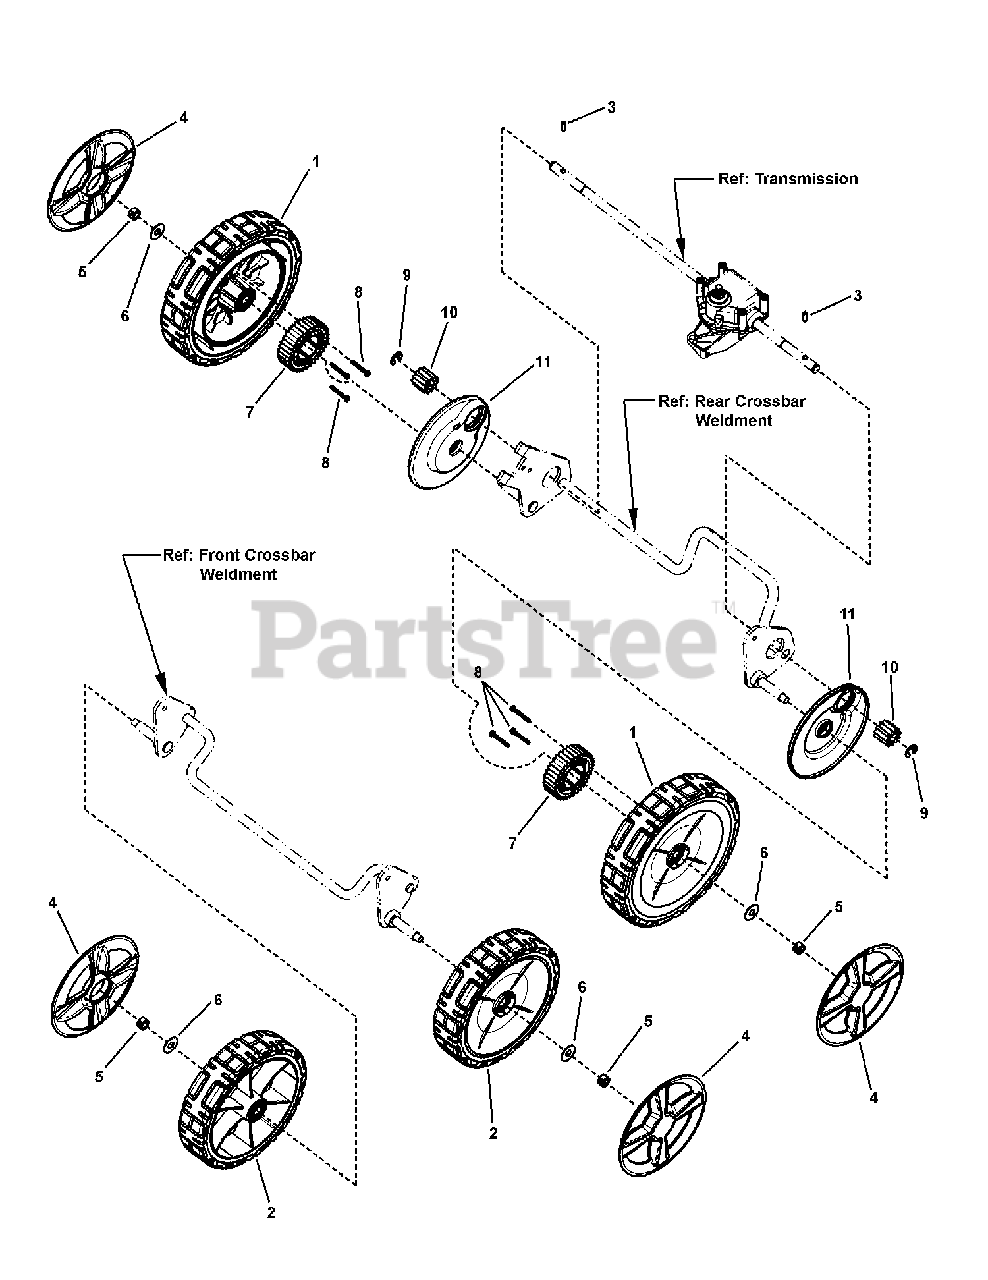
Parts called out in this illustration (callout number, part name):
1	ASSEMBLY, Wheel, 9 x 2 W/BB, Gray
2	ASSEMBLY, Wheel, 8 x 2 W/BB, Gray
3	PIN, .187 OD, .625 Long, Axle
4	HUBCAP, 8" & 9" Spoked Wheel, Cool Gray
5	NUT, 3/8-16 Hex Center Lock, YZ
6	WASHER, 1" OD x .387 ID, FLAT
7	GEAR, 34 T, External Wheel
8	SCREW, #8 x 1-1/4 Hi-Lo, Hex Washer Self-Tap
9	RETAINING RING, .392 ID EXT, .042 Thk
10	GEAR, Pinion, 11 T
11	DUST SHIELD, 21" WBM, RD
